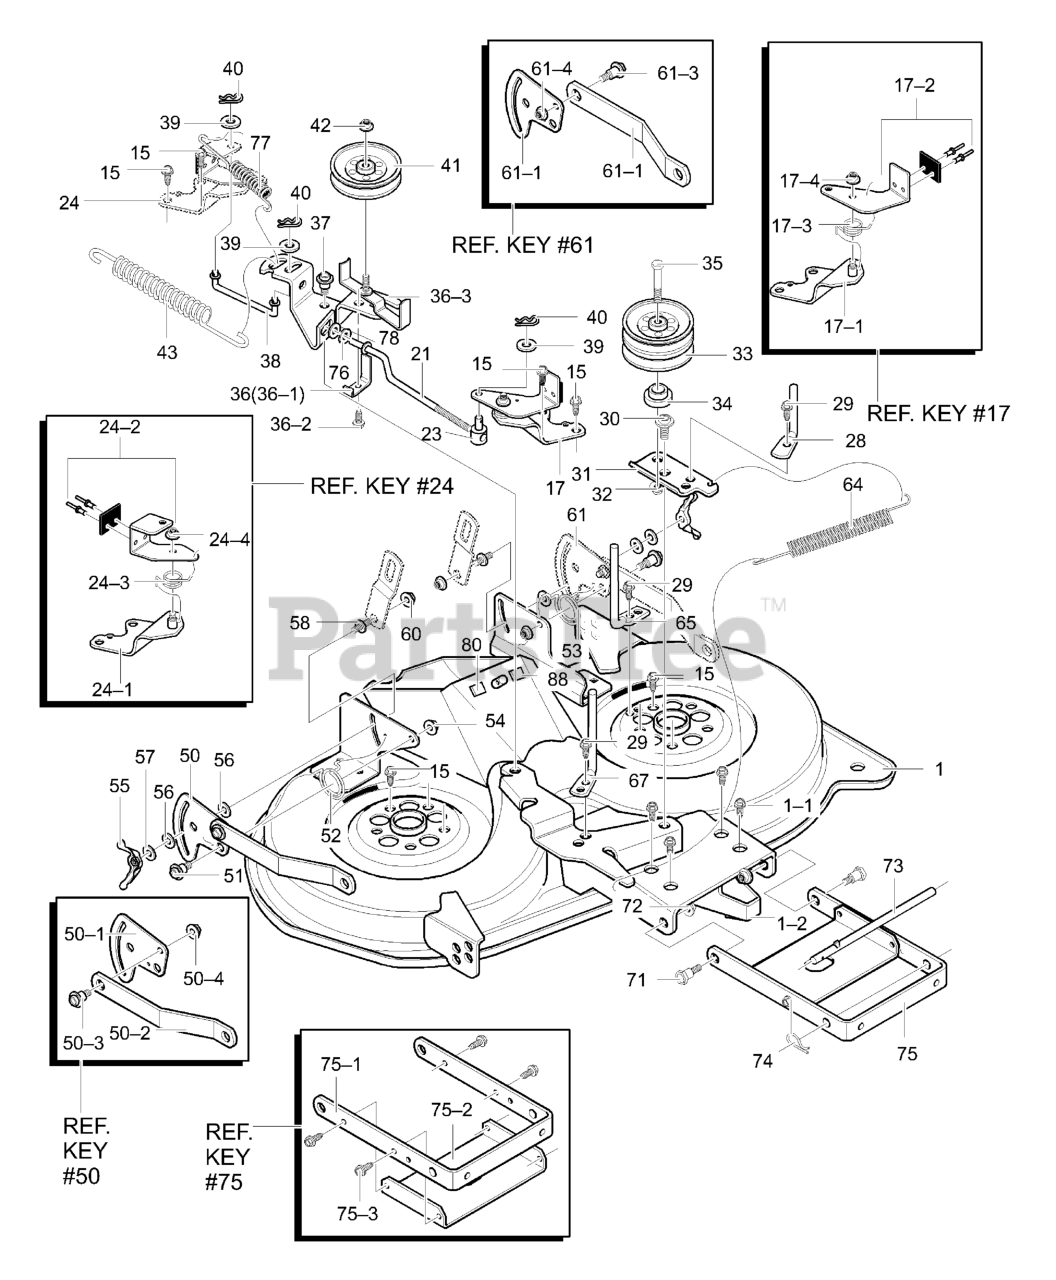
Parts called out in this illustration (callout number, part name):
1	Housing, 40" Deck
1-1	Screw, 5/16-18 x 0.75
1-2	Bracket, Center Strip
17	Brake Arm Assembly LH
17-1	Brake Support Assembly LH
17-2	Brake Arm
17-3	Spring, Torsion
17-4	Nut, 5/16-18
21	Link, Brake LH
23	Nut, Adjusting
24	Brake Arm Assembly RH
24-1	Brake Support RH
24-2	Brake Arm RH
24-3	Spring, Torsion
24-4	Nut, 5/16-18
28	Belt Guide
29	Screw, 5/16-18 x 0.50
30	Bolt, Shoulder
31	Arm, Double Idler
32	Nut, 3/8-16
33	Pulley, Idler Double Vee
35	Screw, 3/8-16 x 3.00
36	Idler Arm Assembly
36-1	Spring - Belt Guide
36-2	Screw, 1/4-20x.50
36-3	Idler Arm
37	Bolt, Shoulder
38	Link, Brake RH
39	Washer, Flat
40	Hair Pin
41	Pulley, Idler
42	Nut, 3/8-16
43	Spring, Extension
50	Assy, Plate,Rear Sus Bkt RH
50-1	Plate-Suspension
50-2	Suspension Bracket Rear
50-3	Bolt, Shoulder
50-4	Nut, 3/8-16
51	Bolt, Shoulder
52	Spring, Torsion RH
53	Spring, Torsion LH
54	Nut, 3/8-16
55	Wingnut, 5/16-18
56	Pad, Friction
57	Washer
58	Pin, Hanger
60	Nut, 3/8-16
61	Assy., Plate Rear Sus Brkt., LH
61-1	Plate-Suspension
61-2	Suspension Bracket, Rear
61-3	Bolt, Shoulder
61-4	Nut, 3/8-16
64	Spring, Extension
65	Belt Guide
67	Belt Guide
71	Shoulder Bolt
72	Nut, 3/8-16
73	Rod, Hanger
74	Hair Pin
75	Assembly, Bracket & Stiffener
75-1	Bracket, Front Suspension
75-2	Stiffener
75-3	Screw, 5/16-18 x 0.75
76	Flatwasher
77	Spring, Extension
78	Washer, Flat
80	Pad, Adhesive
